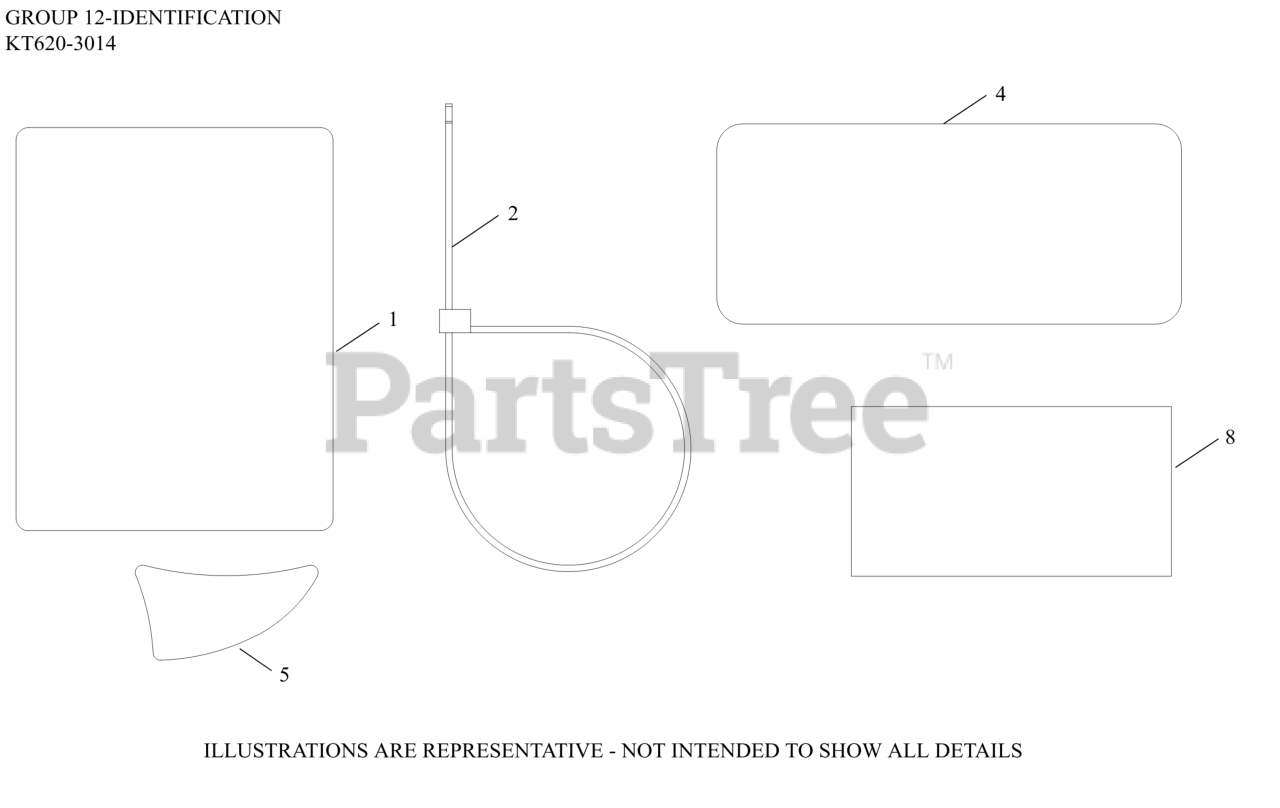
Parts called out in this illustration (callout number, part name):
1	LABEL, CLEAR LAMINATION
4	LABEL, CANADIAN COMPLIANCE
5	LABEL, SMART CHOKE
8	DECAL, USA
